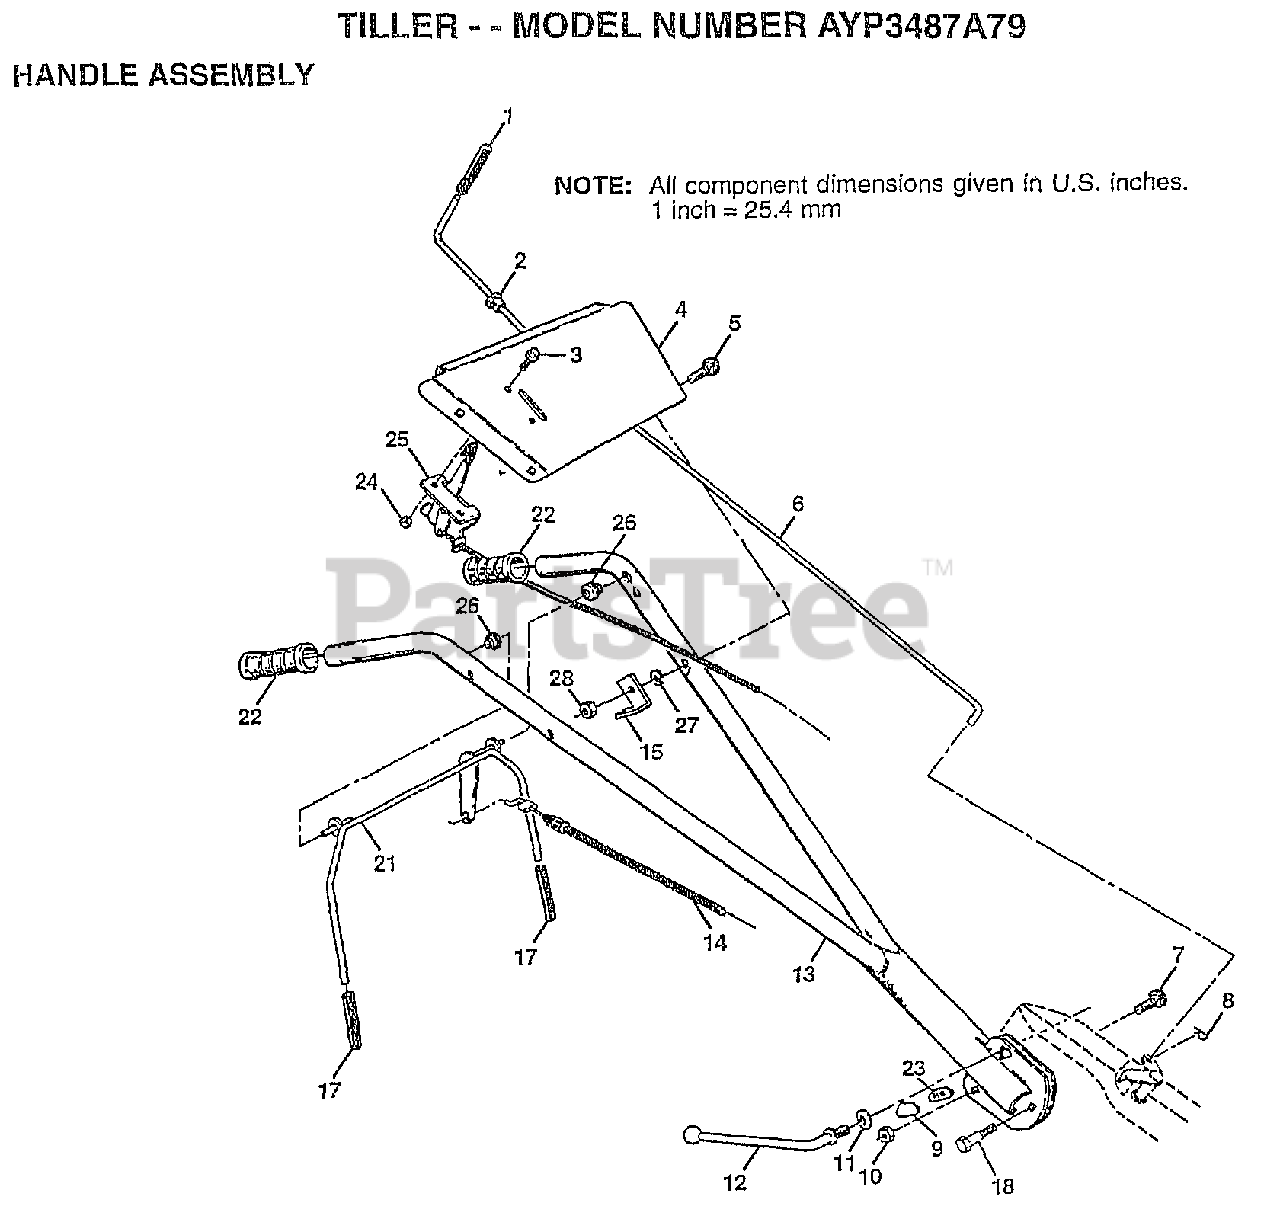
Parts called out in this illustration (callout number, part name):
1	GRIP TI
2	BUSHING
3	SCREW.PNHD.10-24
4	HANDLE BRACKET
5	BOLT CARRIAGE CRT
6	ROD SHIFT CRT
7	BOLT D
8	RETAINER M
9	LOCK CRT
10	LOCKNUT
11	LEVER LOCK CRT
12	LEVER LOCK CRT
14	CABLE.CLUTCH.Z-BE
15	BRACKET.CLUTCH.CA
17	GRIP BAR CRT
18	BOLT PIVOT
21	BAR.ASM.CNTRL.VPL
22	"GRIP,HANDLE"
23	LOCK.HANDLE
25	CONTROL.THROTTLE
26	GROMMET.HANDLE.V-
27	LOCKWASHER
28	NUT
